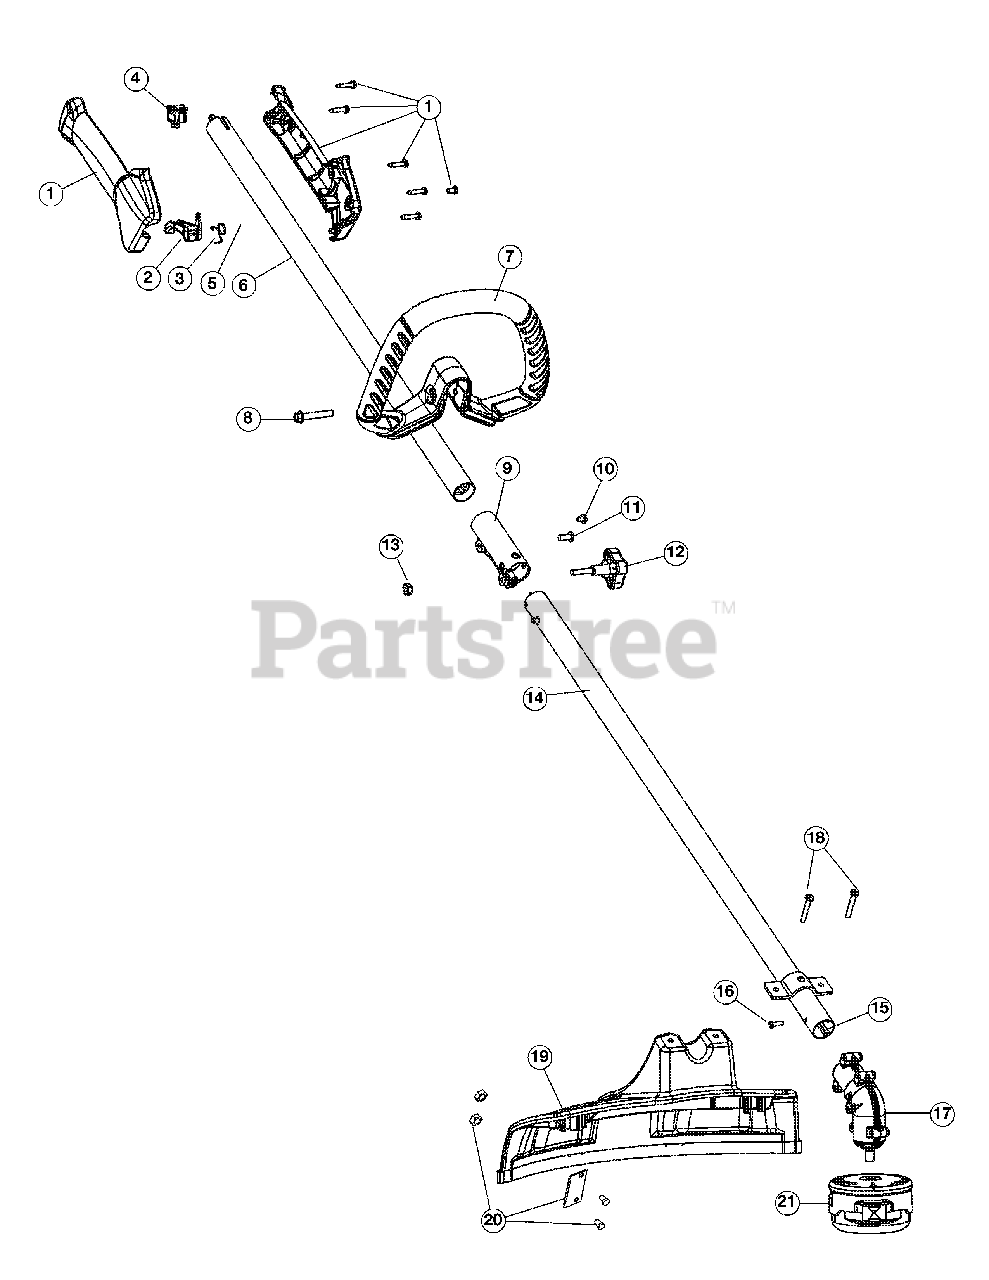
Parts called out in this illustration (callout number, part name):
1	Throttle Housing Assembly (includes 2-4)
2	Throttle Trigger
3	Throttle Trigger Spring
5	Throttle Cable Assembly
6	Upper Drive Shaft Housing Assembly
7	Deluxe D-Handle Assembly (includes 8)
9	Split Boom Coupler (includes 10-13)
12	Adjustment Knob (includes 13)
13	Knob Retaining Nut
14	Lower Drive Shaft Housing Assembly
15	Lower Flexible Drive Shaft
16	Anti-Rotation Screw
17	Gear Box Assembly (includes 16)
18	Shield Mounting Screws
19	Shield Assembly (includes 20)
20	Blade Assembly
21	Cutting Head Assembly
